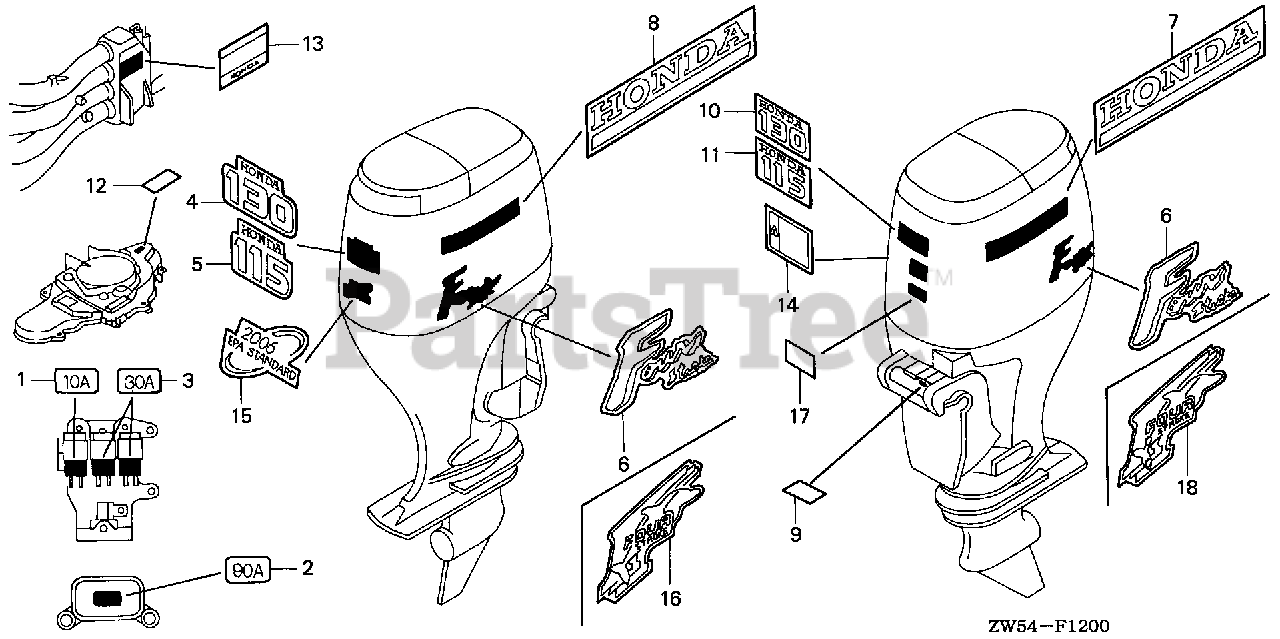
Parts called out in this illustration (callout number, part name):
1	MARK, FUSE (10A)
2	MARK, FUSE (90A)
3	MARK, FUSE (30A)
5	MARK, RR. (BF115)
6	MARK, SIDE
7	MARK, L. SIDE STRIPE
8	MARK, R. SIDE STRIPE
9	LABEL, SPECIFICATION (NMMA)
11	MARK, FR. EMBLEM (BF115)
12	LABEL, OIL CAUTION (ENGLISH)
13	MARK, MUFFLER
14	LABEL, WARNING OPERATOR (ENGLISH)
15	MARK, ENVIRONMENT (EPA 2006)
